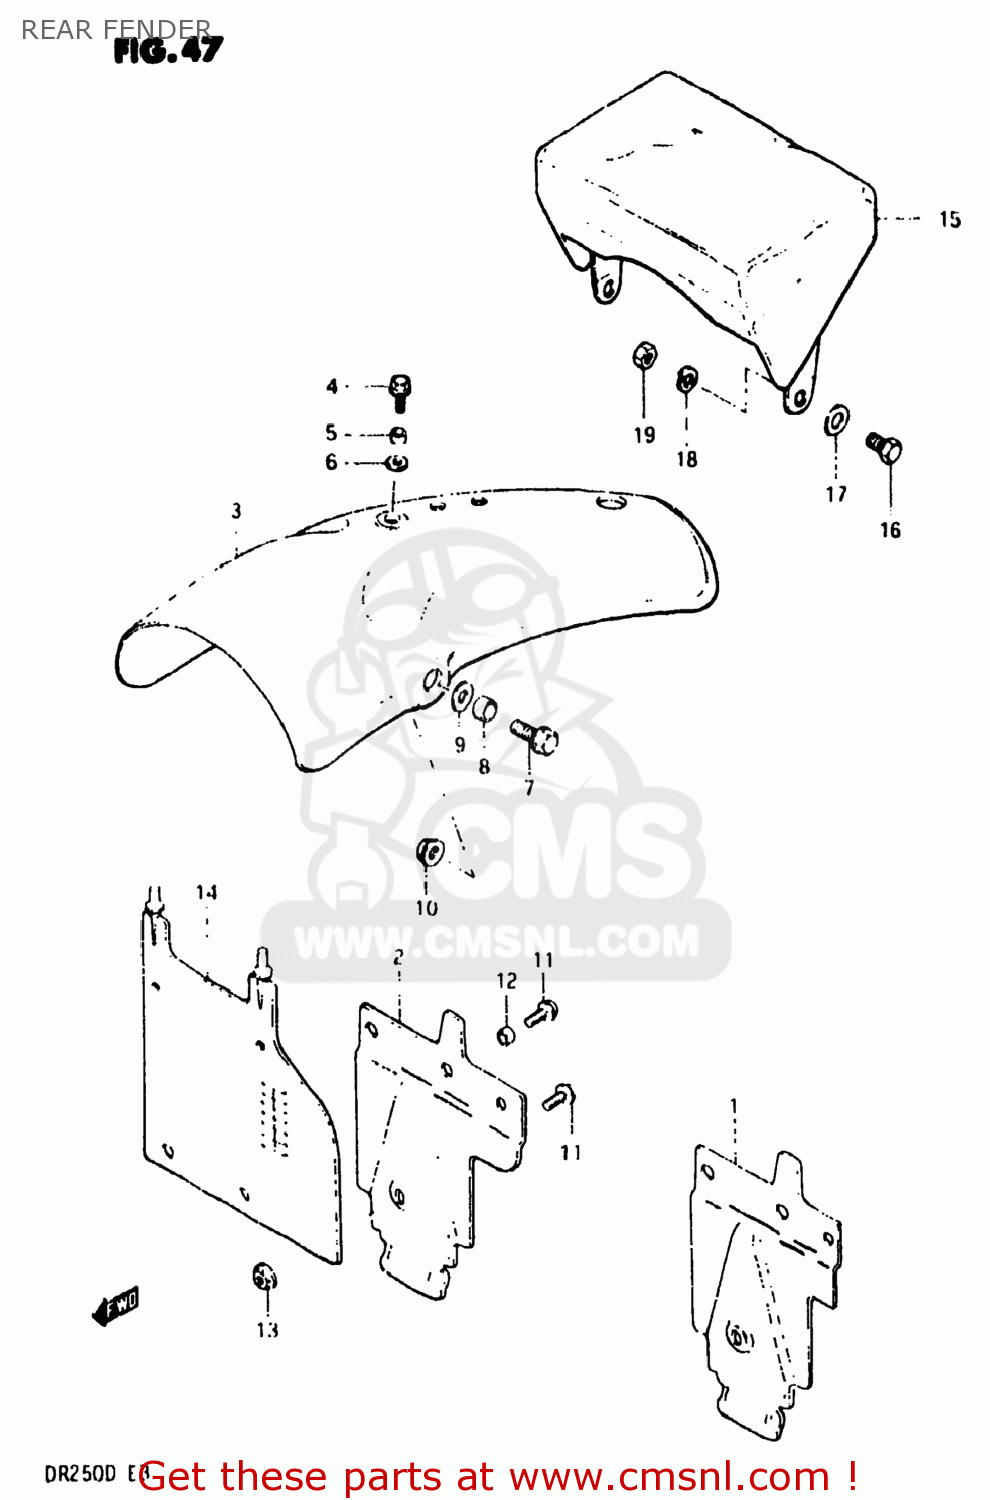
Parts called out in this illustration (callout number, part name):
1	FENDER,REAR
2	FENDER,REAR
3	FENDER,REAR
4	BOLT
5	SPACER
6	WASHER
7	BOLT
8	SPACER(8.2X14X4.5)
9	WASHER (8.7X22X2)
10	NUT
11	SCREW, FRONT
12	SPACER
13	NUT
14	MUD GUARD,REAR FENDER
15	BAG ASSEMBLY,SEAT TAIL
16	BOLT
17	WASHER
18	LOCK WASHER
19	NUT
